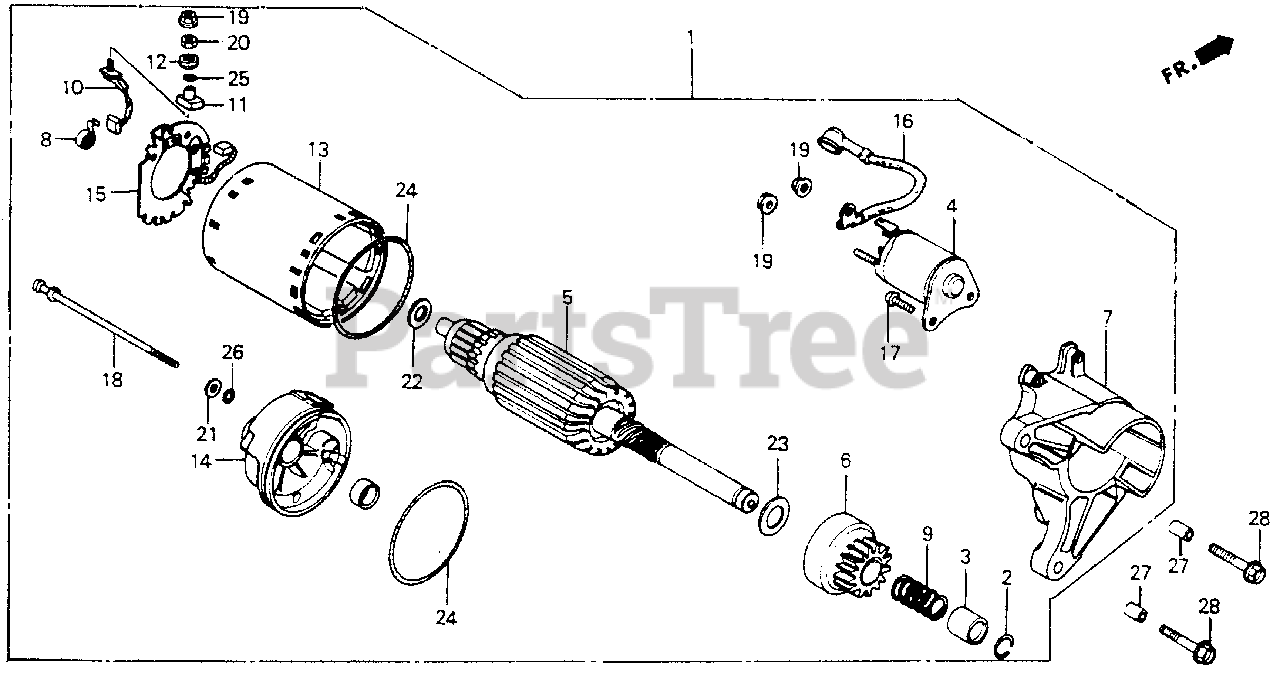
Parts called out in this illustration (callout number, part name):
1	MOTOR ASSY., STARTER
2	RING, SNAP
3	COLLAR, CLUTCH
4	CONTACTOR ASSY.
6	CLUTCH, OVERRUNNING
7	HOUSING, DRIVE SIDE
8	SPRING, BRUSH
10	BRUSH
11	BUSHING, INSULATION
12	BUSHING, INSULATION
13	YOKE
14	FRAME, STARTER END
15	PLATE, BRUSH HOLDER
16	WIRE, WATER COVER (NOT AVAILABLE)
16	WIRE, WATER COVER
17	BOLT
18	BOLT, THROUGH (NOT AVAILABLE)
21	WASHER, STEEL PLATE
22	WASHER
25	O-RING
27	PIN A, DOWEL (10X16)
28	BOLT, FLANGE (8X35)
